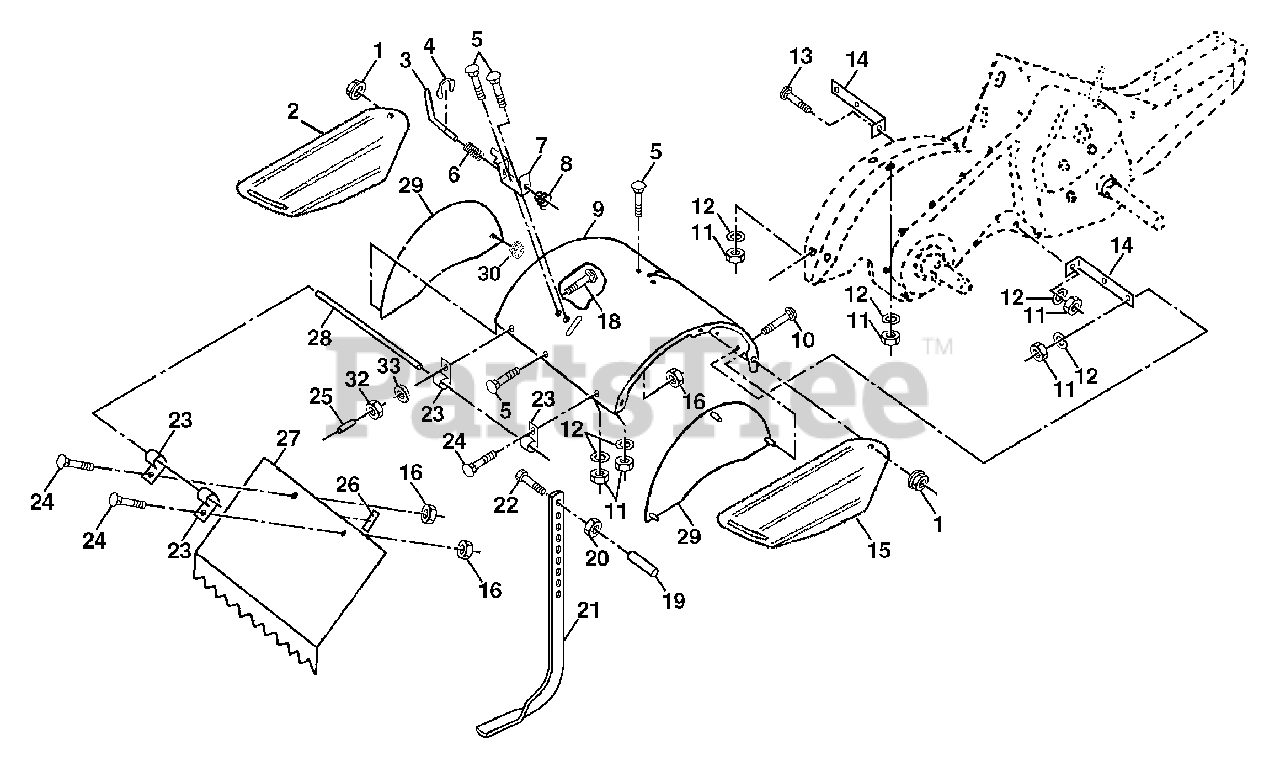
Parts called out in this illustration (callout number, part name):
1	Nut, Flange 5/16-18
2	Shield, Side, Outer, L.H.
3	Pin, Depth Stake
4	Ring, Klip
5	Bolt, Carriage 5/16-18 x 1
6	Spring
7	Bracket, Latch
8	Spring, Depth Stake
10	Bolt, Carriage 5/16-18 x 3/4 Gr. 5
11	Nut, Hex 5/16-18
12	Washer, Lock 5/16
14	Bracket, Shield Tine
15	Shield, Side, Outer R.H.
18	Bolt, Carriage 1/4-20 x 1-1/4 Gr. 5
19	Grip
20	Nut, Hex 3/8-16
21	Stake, Depth
22	Bolt, Hex 3/8-16 x 2
23	Hinge
24	Bolt, Carriage 1/4-20 x 1/2
25	Cap, Vinyl
26	Pad, Idler
27	Shield, Leveling
28	Pin, Hinge
30	Nut Lock Hex Flange
32	Nut, Fin, Hex, 1/4-20
33	Washer, Lock 1/4
